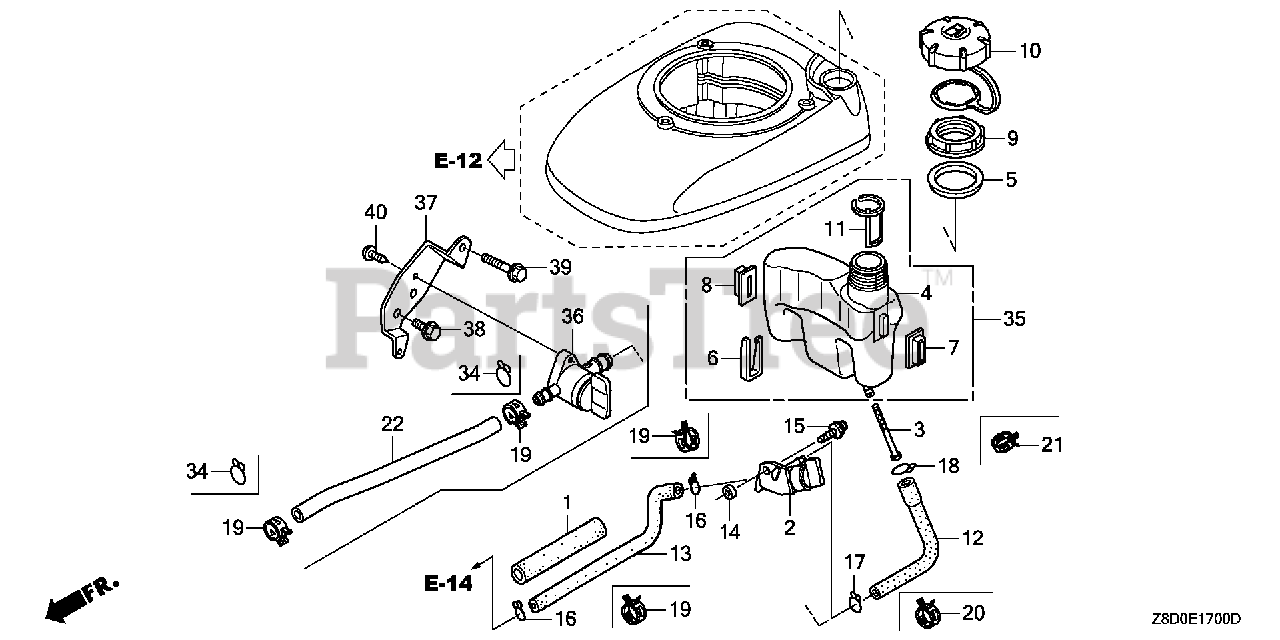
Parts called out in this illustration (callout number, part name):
1	RUBBER, SUPPORTER (107MM)
2	PETCOCK ASSY.
3	FILTER, FUEL
5	SEAL, FUEL FILLER NECK
6	CLIP, TANK MOUNTING
9	NUT, TANK MOUNTING
10	CAP ASSY., FUEL TANK
11	GAUGE, FUEL LEVEL
12	TUBE, FUEL TANK
12	TUBE, FUEL TANK (FKM)
13	TUBE, FUEL
13	TUBE, FUEL (FKM)
14	COLLAR, FR. TURN SIGNAL
15	SCREW-WASHER (5X10)
16	CLIP, TUBE (B8)
17	CLIP, TUBE (B10)
18	CLIP, TUBE (C11)
19	CLAMP, TUBE (D8)
20	CLAMP, TUBE (D10)
21	CLAMP, TUBE (D12)
35	TANK KIT, FUEL
